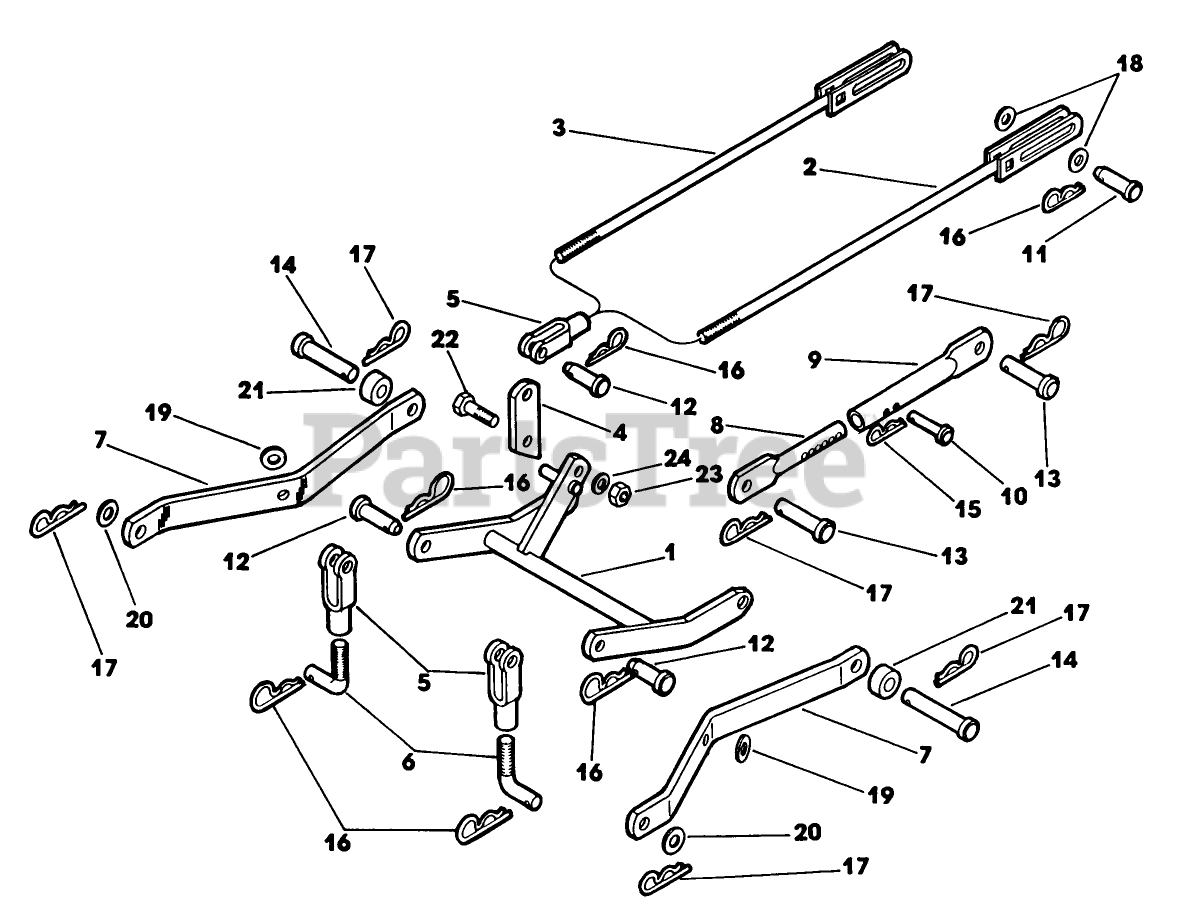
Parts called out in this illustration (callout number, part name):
2	ROD AY - LIFT
4	ARM-LIFT
7	LINK-LIFT
8	LIFT LINK-INSIDE
9	LIFT LINK-OUTSIDE
12	PIN CLEVIS
13	PIN-CLEVIS
15	PIN-HAIR
16	PIN - SPRING CLIP
